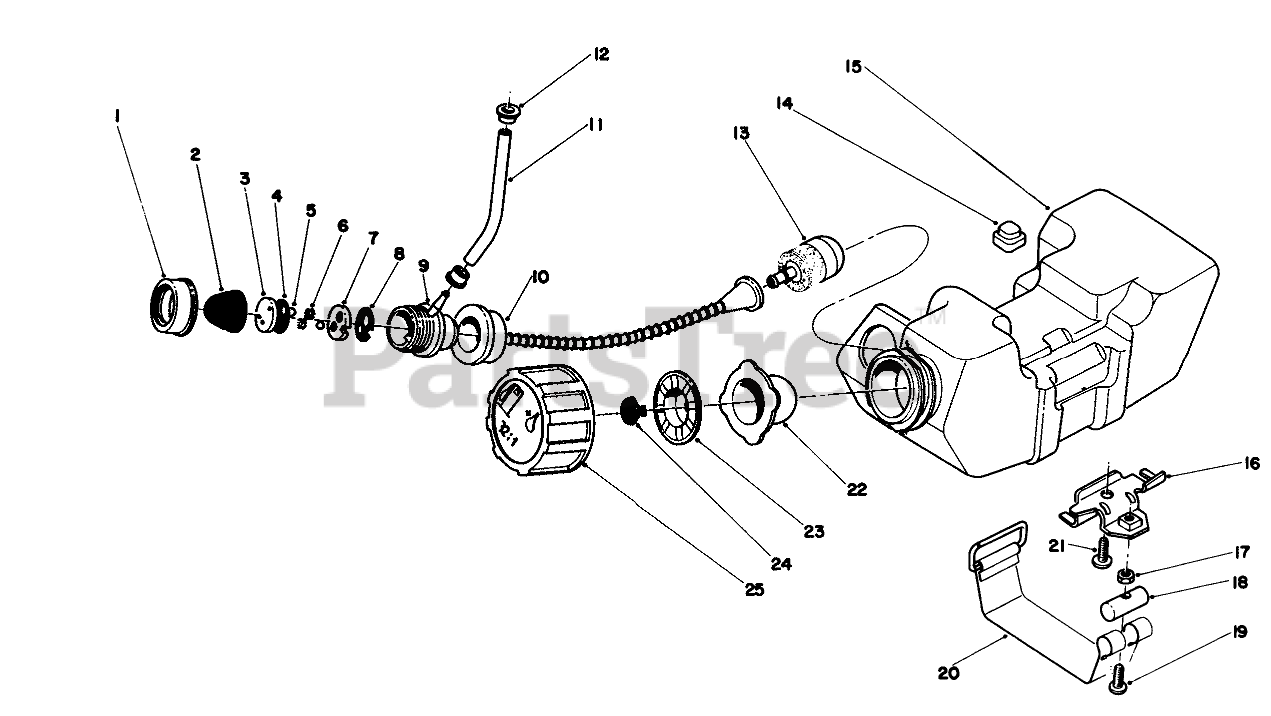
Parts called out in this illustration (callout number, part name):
1	PUMP CAP
3	SEAT VALVE
4	GASKET
6	SPONGE
7	SEAT VALVE
8	GASKET
9	Pump-Primer (Incl.Ref. #2-8)
10	HOSE, SUCTION
11	Tube-Fuel
13	FUEL FILTER
15	Fuel Tank Assembly (Incl.Ref. #1-10, 13, 21-24)
16	HANGER, TANK
19	Screw
20	BAND, TANK
21	Screw
22	GASKET - PACKING
23	HOLDER
24	BREATHER VALVE
25	TANK CAP
